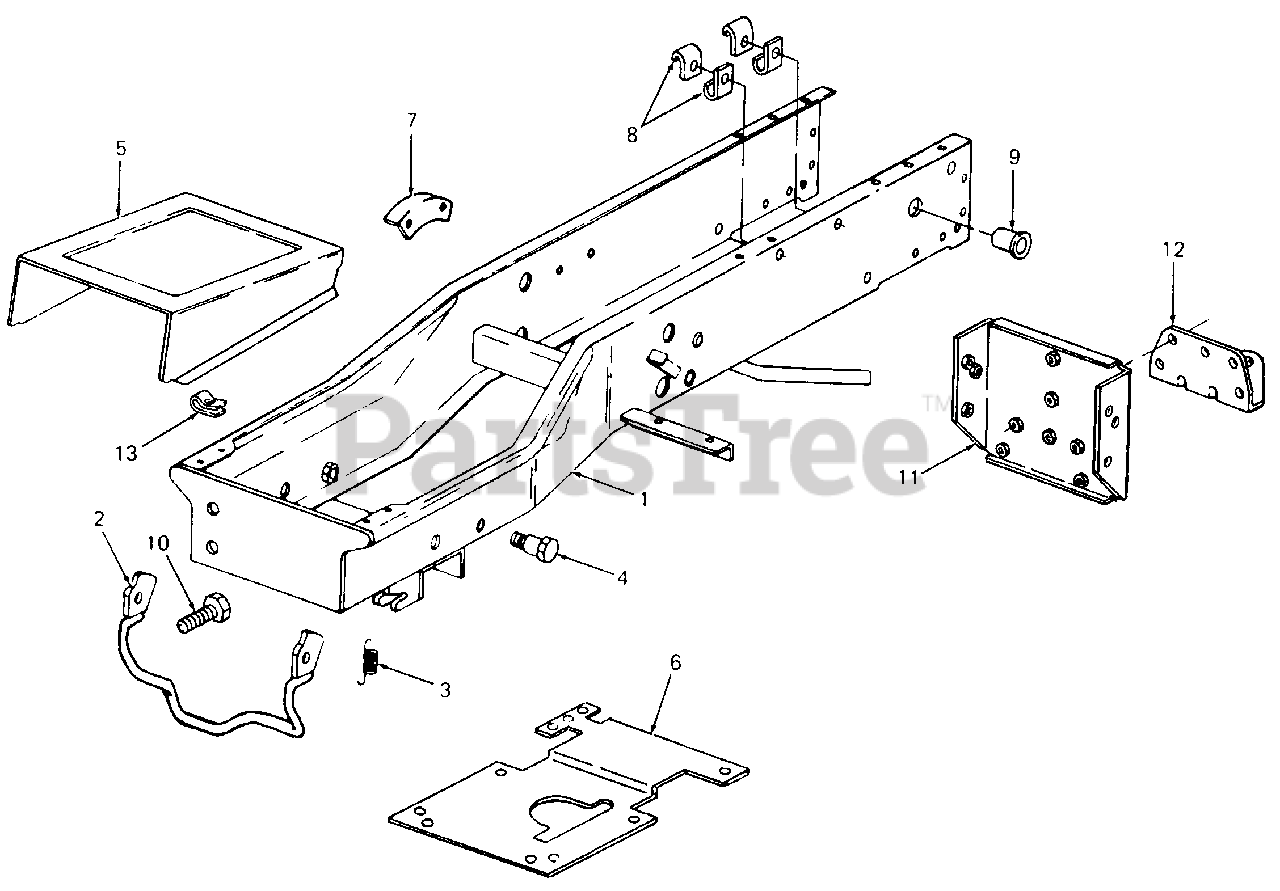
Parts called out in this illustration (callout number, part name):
1	Frame Assy
3	Spring, Latch
4	Bolt, Shoulder
5	Cover, Frame w/Graphic
7	Bracket, Height Indicator
8	Clip, Cable
9	Bushing, Snap
10	Screw, Adjustment, 1/2-20 X 1.0 Lg GR5
11	Plate Assy, Hitch
13	Nut, Speed
